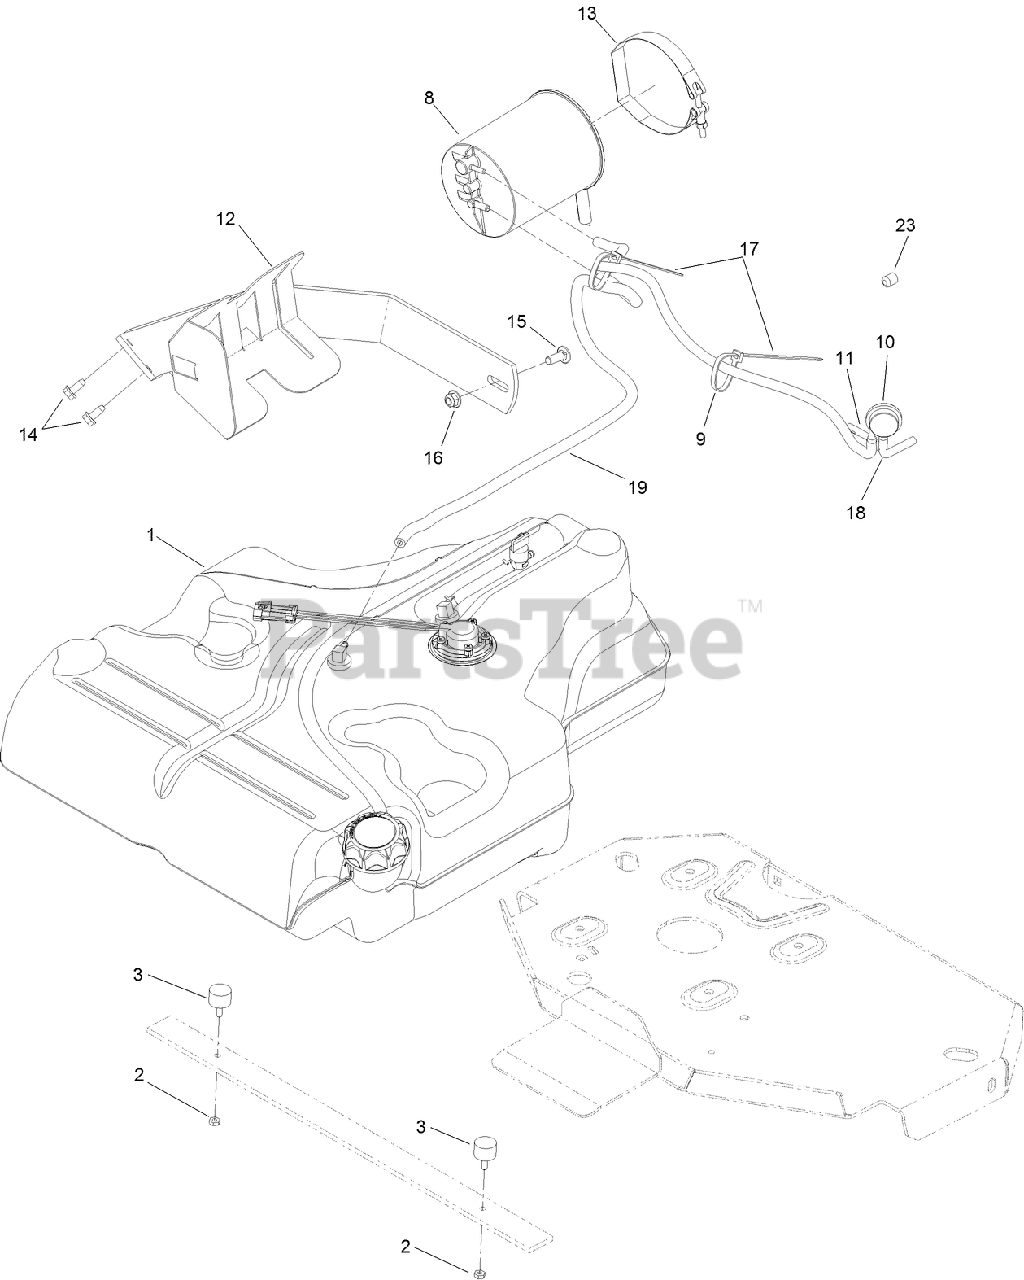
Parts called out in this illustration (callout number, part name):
1	FUEL TANK ASM
2	NUT-JAM
3	BUMPER-RUBBER (W/ STUD)
8	CANISTER-CARBON, 1200CC
9	HOSE-VENT, FORMED
10	VALVE-CONTROL, VACUUM
11	HOSE-VENT, FORMED
12	MOUNT-CANISTER
13	CLAMP-T-BOLT
14	SCREW-HWHTF
15	SCREW-CARR
16	NUT-HF, NI
17	TIE-PLASTIC
18	HOSE-VENT, FORMED
19	HOSE-FUEL
23	PLUG-PORT
